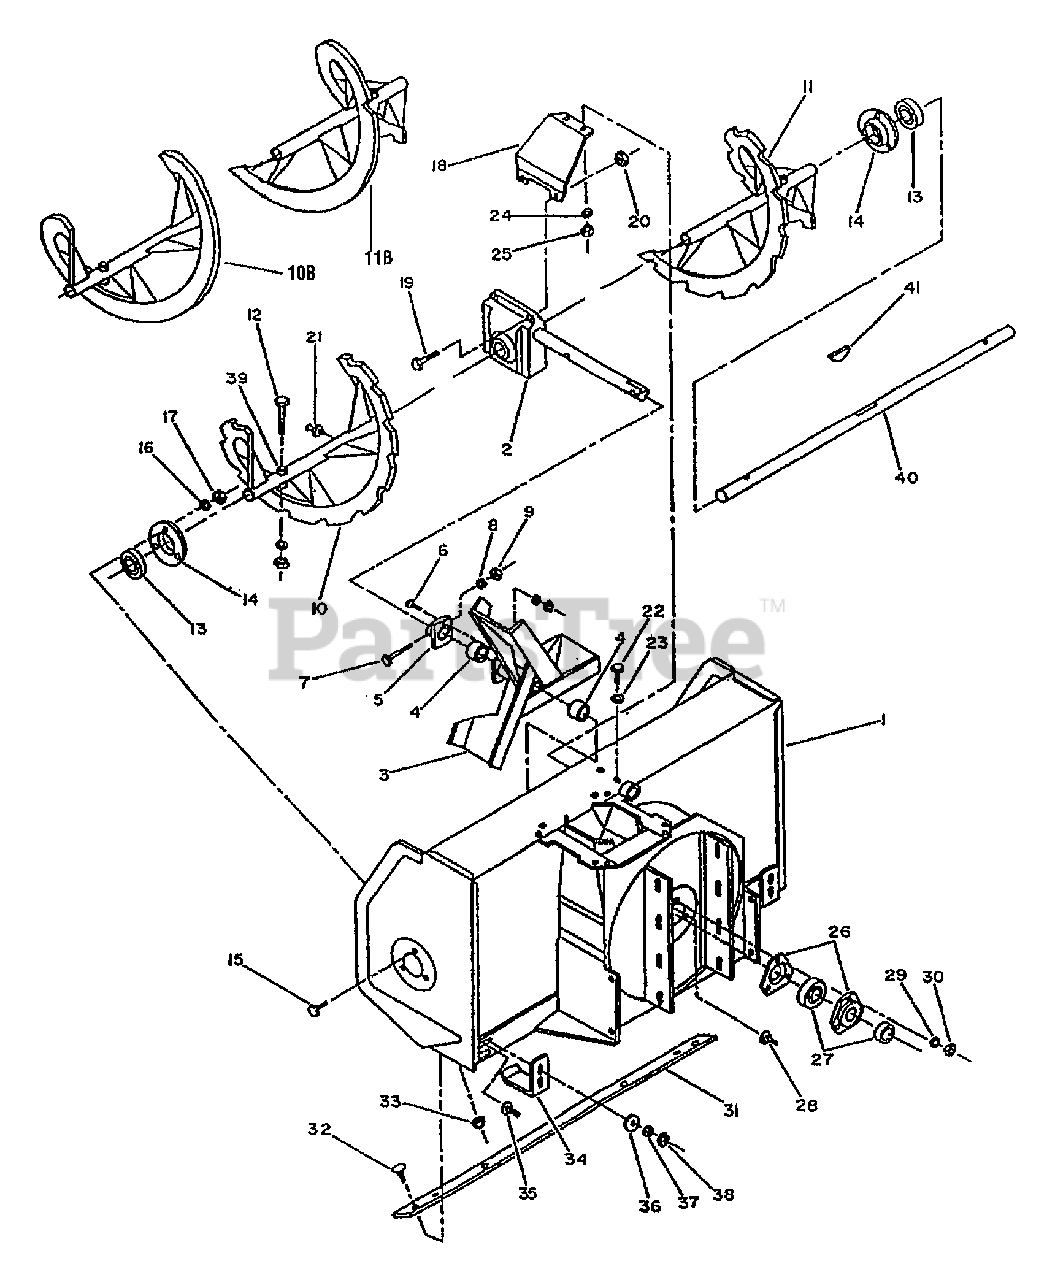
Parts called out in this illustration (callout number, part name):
2	ASSM-WORM GEAR
3	ASSM-FAN
4	BUSHING
7	SCR-HH 5/16-18X2.00
8	WASHER-LK .312 ZP
9	NUT-HEX 5/16-18 ZP
10	AUGER-LH SCALLOP 46"
10B	AUGER-RH
11	AUGER-RH SCALLOP 46"
11B	BOLT-SHEAR
12	BOLT-SHEAR
14	FLANGE
15	SCR-HHC 5/16-18X.75 GR 5 ZP
16	WASHER-LK .312 ZP
17	NUT-HEX 5/16-18 ZP
19	SCR-HH 5/16-18X1.25 G5ZP
20	NUT-H/LK 5/16-18 NYLOCK
21	FITTING
22	SCR-HHC 5/16-18X.75 GR 5 ZP
23	WASHER-FLAT 3/8 SAE
24	WASHER-LK .312 ZP
25	NUT-HEX 5/16-18 ZP
27	BRG W/COLLAR
28	SCR-CARR 5/16-18X.75 G2 ZP
29	WASHER-LK .312 ZP
30	NUT-HEX 5/16-18 ZP
31	BAR-SCRAPER
32	SCR-CARR 5/16-18X.75 G2 ZP
33	NUT-HEX 5/16-18 ZP
34	SHOES-SKID
35	SCR-CARR 5/16-18X1.0 G2 ZP
36	WASHER-FLAT 3/8 SAE
37	WASHER-LK .312 ZP
38	NUT-HEX 5/16-18 ZP
39	BUSHING
40	SHAFT-OUTPUT
41	KEY-WOODRUFF
